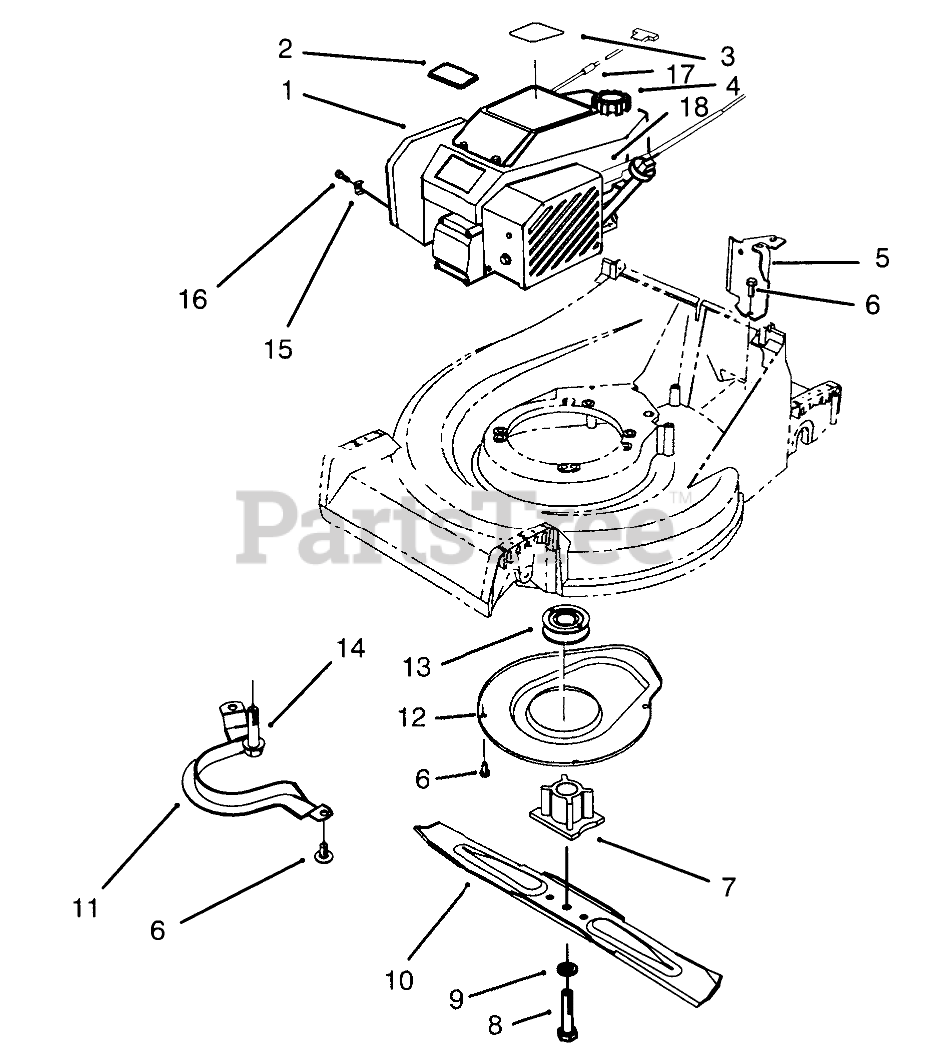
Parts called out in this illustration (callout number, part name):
1	Engine
2	PLATE-LOGO
3	DECAL - ENGINE
4	CAP-GAS
5	Bracket-Cable Support
6	SCREW-HWHTF
7	BLADE RETAINER
8	SCREW-BLADE
9	WASHER-LOCK
10	Key
11	Guide-Belt
12	Cover
13	PULLEY-DRIVE, ZONE START
14	SCREW-HWH
15	CLAMP-CASING
16	CLAMP SCREW F/W ENGINE
17	STOP-ROPE
18	COVER - BRAKE F/W
